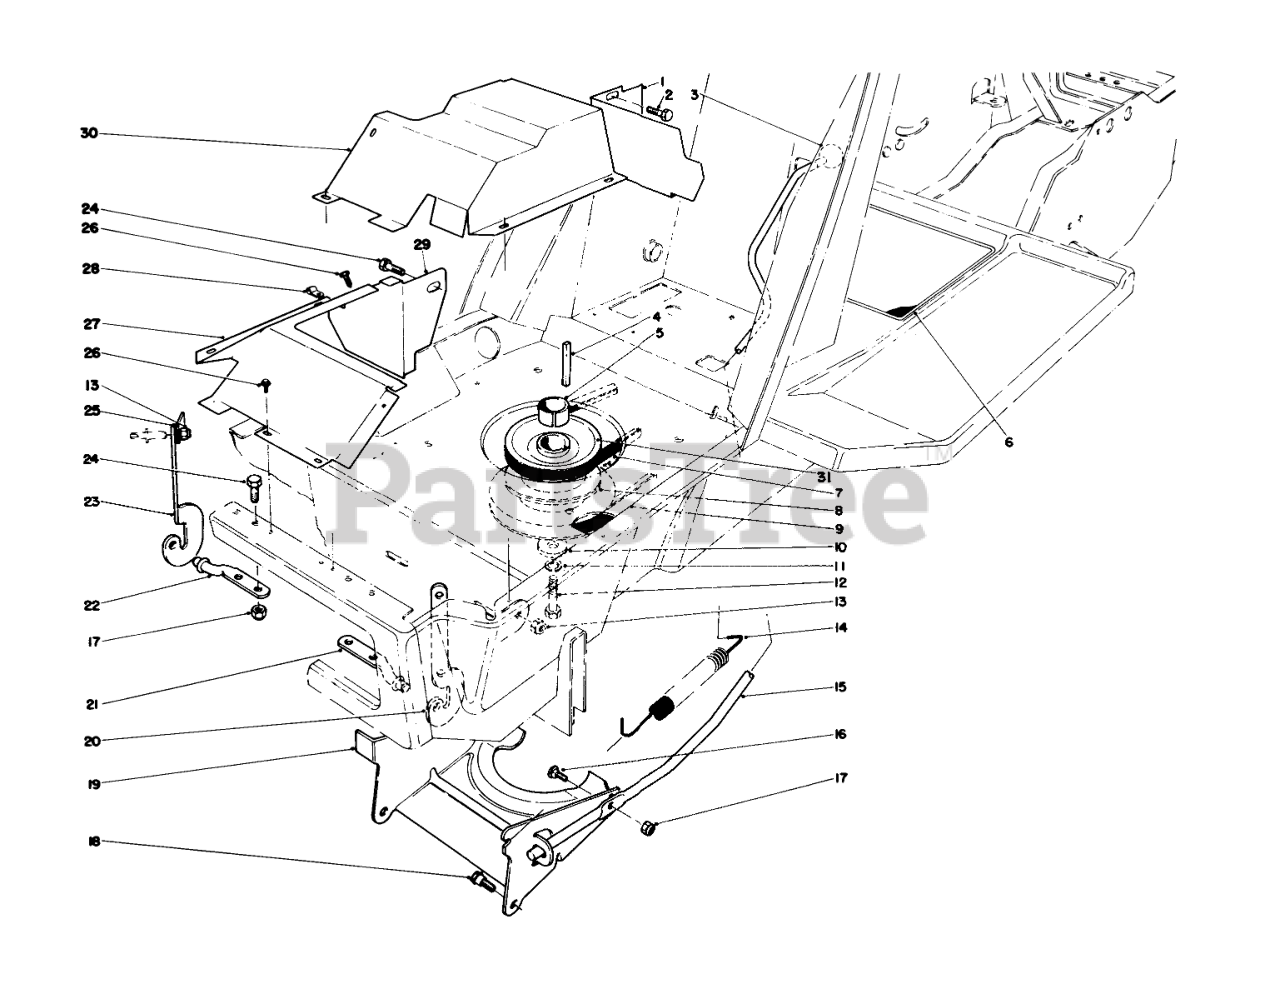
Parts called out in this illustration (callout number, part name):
1	EXH SHIELD SUPT B
2	SCREW-HH
4	KEY-SQUARE
5	PULLEY SPACER
6	OPERATION DECAL
7	V BELT
8	Clutch & Brake-Deck
9	V BELT
10	WASHER
11	WASHER-LOCK
12	SCREW-HH
13	NUT-LOCK, CONE
14	TRACTION SPRING
15	Engagement Lever
16	SCREW-HH
17	NUT-LOCK, CONE
18	SCREW-SHOULDER
19	Actuator Clutch
20	Bracket-Hinge L.H.
21	LH HOOD HINGE PIN
22	RH HOOD HINGE PIN
23	RH HINGE BRKT
24	SCREW-HH
25	SCREEN SUPT BRKT
26	SCREW-HWHTF
27	Heat Shield
28	CABLE CLAMP
29	Support Heat Shield
30	HEAT SHIELD WA B
31	TOP SHEAVE
